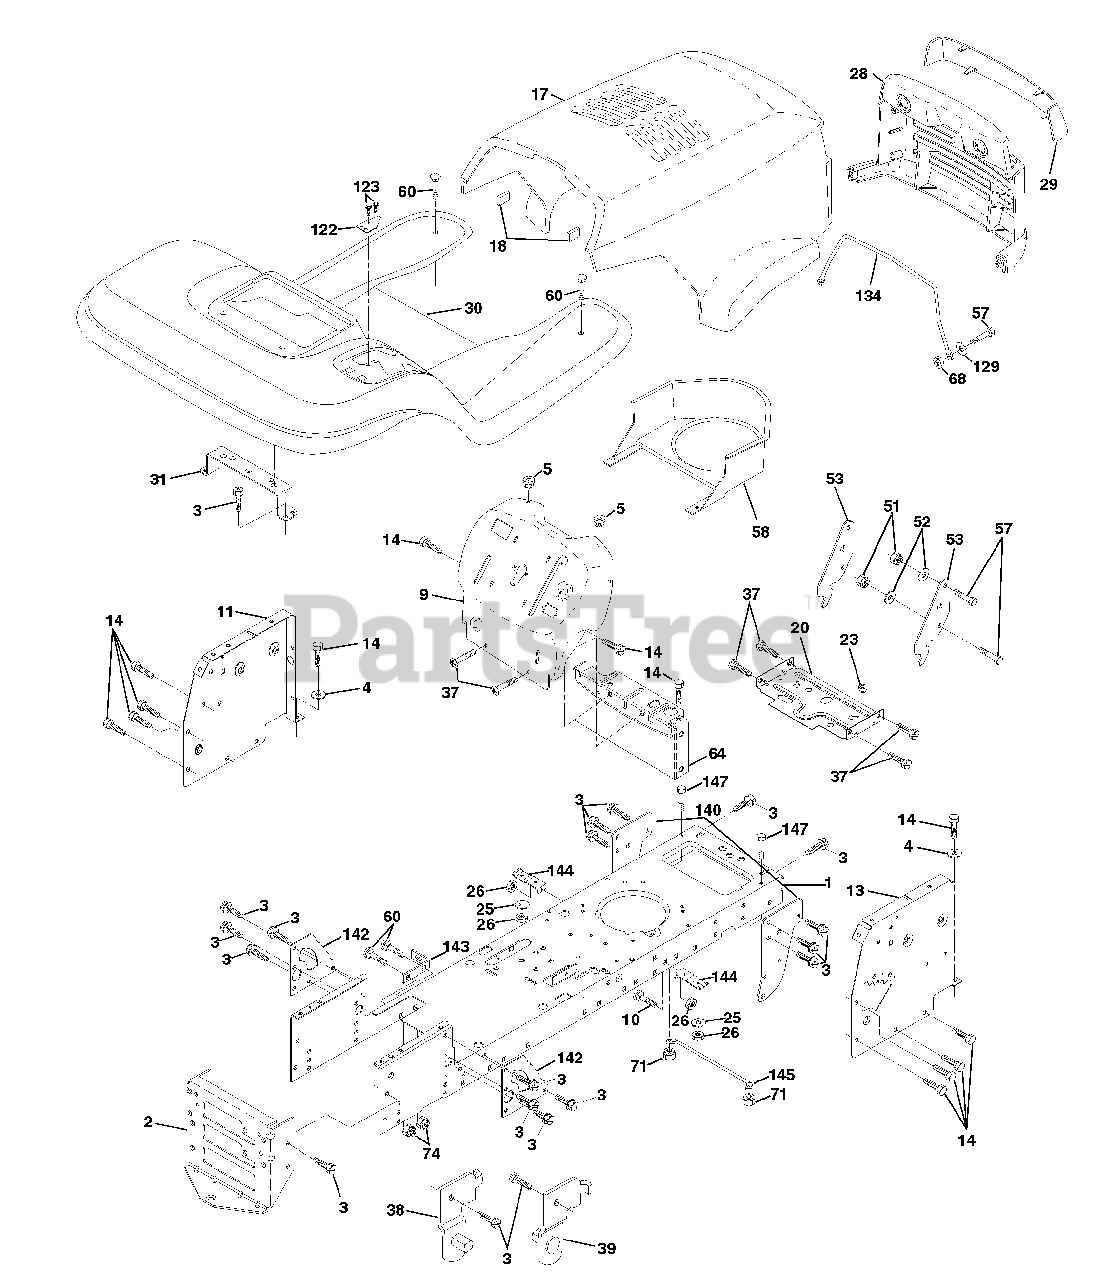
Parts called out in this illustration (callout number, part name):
1	Chassis Weldment
2	Drawbar, Stretch
3	Screw Thdrol 3/8-16x3/4 Ty-tt
4	Washer 13/32 x 3/4 x 16 Ga.
5	Bumper Hood/Dash
9	Dash P/L M, N/AMM N/HM Grey
10	Bolt Carriage 3/8-16 x 1
11	Panel Dash Lh
13	Panel Dash Rh
14	Screw Thdrol 3/8-16 x 1/2 Ty-tt
17	Hood LT/PL Husqvarna
18	Bumper Hood
20	Plate Mtg Battery Fuel Tank Fr
25	Washer 13/32 X 13/16 X 12 Ga
26	Nut Lock Hex W/Ins 3/8-16 Unc
28	Grille LT/PL Husqvarna
29	Lens LT/PL Husqvarna
30	Fender Footrest STLT Pnt
31	Bracket Support Fender
37	Screw Thdrol 6/16-18 x 1/2 TYT
38	Bracket, Asm. Pivot, L.H., Mower Rear
39	Bracket, Asm. Pivot, R.H., Mower Rear
51	Nut Lock Hex W/Ins 1/4-20
52	Washer 9/32 x 7/8 x 16 Ga.
53	Bracket Pnt. Pick off LT/PL Husqvarna
57	Bolt Hex 1/4-20 x 3/4
58	Air Duct Engine P/L
60	Bolt Rdhd Sqnk 3/8-16unc x 3/4
64	Dash Lower STLT
68	Nut Keps Hex 1/4-20unc
71	Nut Crownlock 1/4-20unc
74	Nut Crownlock 3/8-16 UNC
122	Bracket Shift STLT
129	Washer 9/32 x 5/8 x 16 Ga.
134	Rod Support Hood LT/PL Husq.
140	Bracket Suspension Front
142	Plate Reinforcement STLT
143	Bracket Swaybar Chassis
144	Bracket Pnt Footrest STLT
145	Rod Pivot Chassis/Hood
147	Bolt Hex Hd 1/4-20unc x 3/4
